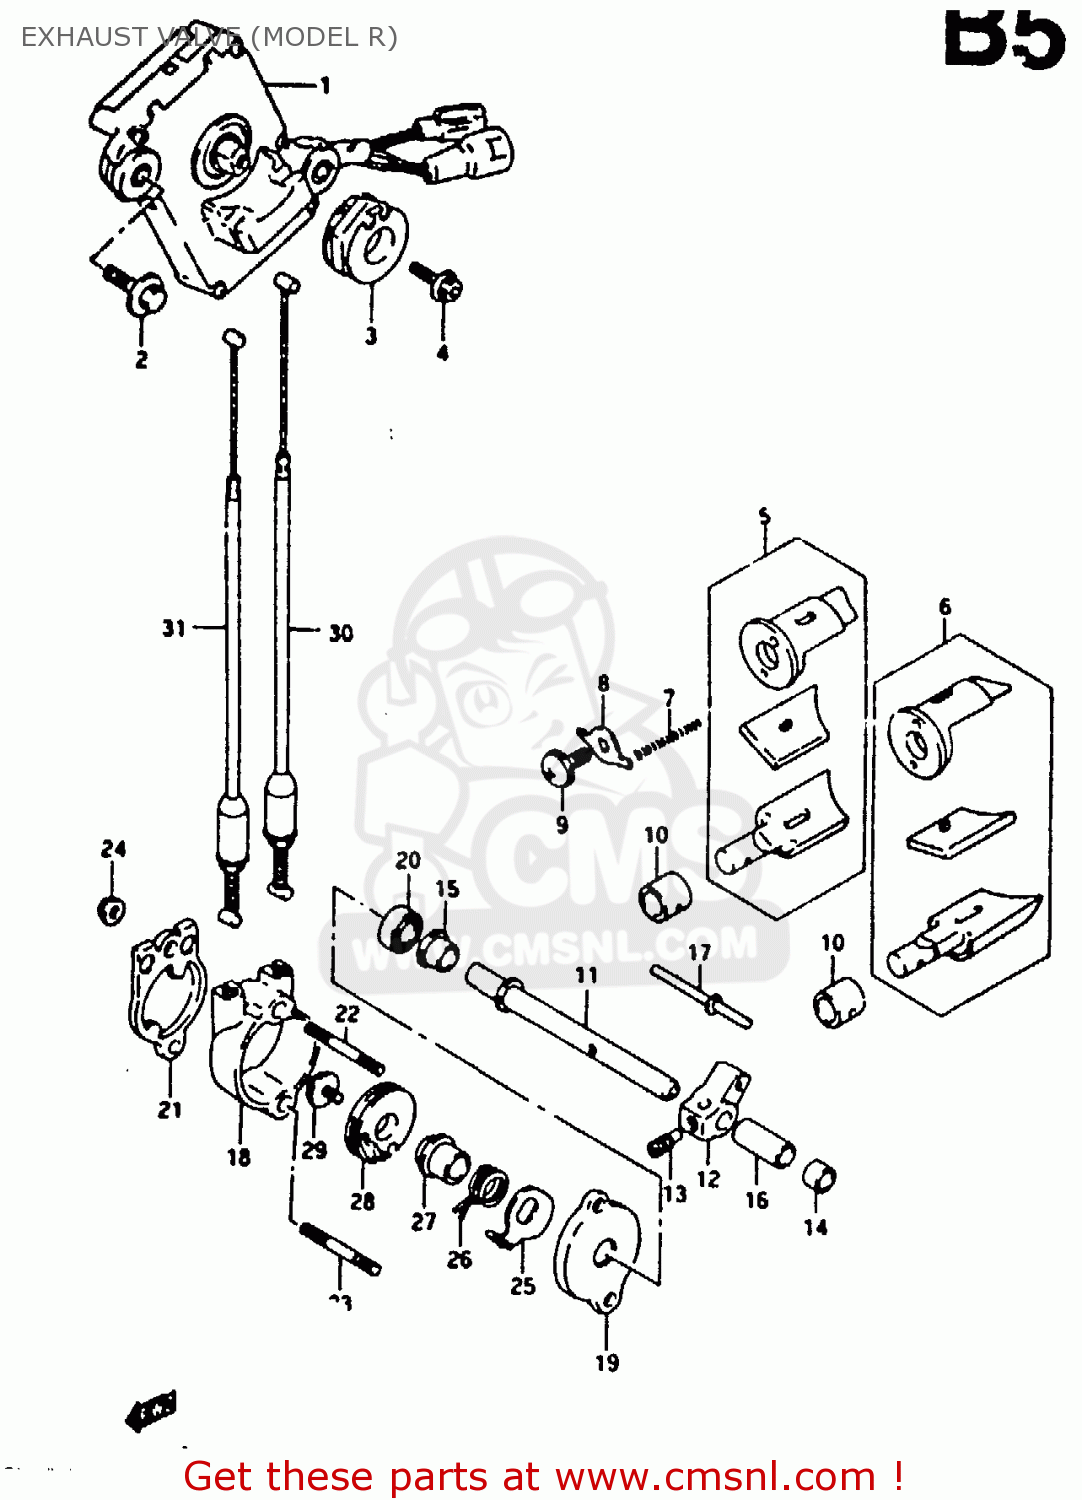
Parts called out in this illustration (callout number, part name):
1	ACTUATOR ASSY
2	BOLT(6X25)
3	PULLEY,CONTROLLER
4	BOLT
5	VALVE ASSY, EXHAUST RH
6	VALVE ASSY, EXHAUST LH
7	SPRING
8	RETAINER,EXHAUST VALVE SPRING
9	SCREW
10	SPACER,EXHAUST VALVE
11	SHAFT,EXHAUST VALVE
12	ARM,EXHAUST VALVE SHAFT
13	SCREW(6X10)
14	BUSH(8X12X7)
15	BUSH,EXHAUST VALVE NO.2
16	SPACER,EXHAUST VALVE SHAFT
17	PIN,EXHAUST VALVE 48.5MM
18	HOLDER,EXHAUST VALVE
19	SPACER, HOLDER BASE
20	SEAL,OIL(8X16X5)
21	COVER,HOLDER
22	BOLT,STUD
23	STUD BOLT
24	NUT
25	LEVER,EXHAUST VALVE
26	SPRING,EXHAUST VALVE LEVER
27	SPACER,EXHAUST VALVE PULLEY
28	PULLEY,EXHAUST VALVE
29	BOLT(5X12)
30	CABLE,EXHAUST VALVE NO.1
31	CABLE,EXHAUST VALVE NO.2
32	PULLEY,EXHAUST VALVE
33	BOLT(5X12)
34	CABLE,EXHAUST VALVE NO.1
35	CABLE,EXHAUST VALVE NO.2
